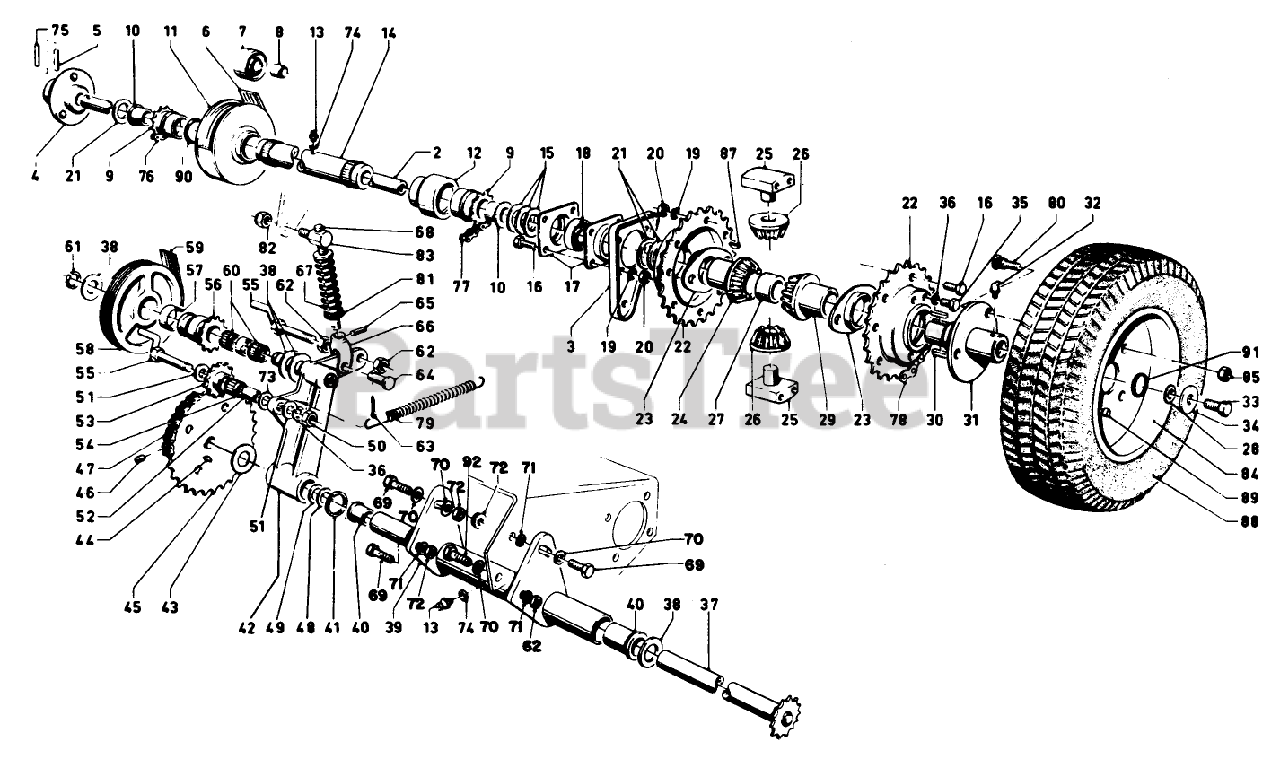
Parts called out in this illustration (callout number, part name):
4	Hub, Right Side
5	PIN-ROLL, SLOTTED
7	REEL IDLER *R
8	TOL RING
10	3/4IDX1LG FLANGE BSHG
13	FITTING-GREASE
15	WASHER-THRUST
16	SCREW-HH
19	WASHER-LOCK
20	NUT-HEX
21	THRUST WASHER
28	WASHER-LOCK, INTERNAL
30	KEY-SQUARE
32	FITTING-LUBE, 45 DEG
33	SCREW-HH
34	WASHER-FLAT
35	SCREW-HH
36	WASHER-LOCK
38	THRUST WASHER
40	Bushing
41	RING-SNAP
43	THRUST WASHER
44	KEY-WOODRUFF
45	LARGE SPROCKET ASM
46	SCREW-SET
47	TRACTION CHAIN
48	THRUST WASHER
49	THRUST WASHER
50	NUT-HEX
51	WASHER-PLAIN
52	SPINDLE
53	Sprocket, Idler (Incl. Ref. #54)
57	Ring Tolerance
58	TRACTION PULLEY
59	TRACTION BELT
60	.625 NEEDLE BEARING
62	NUT-JAM
63	PIN-COTTER
64	PIN-CLEVIS
65	PIN-ROLL, SLOTTED
66	CLEVIS
67	COMP SPRING *R
68	ROD FLANGE WA
69	SCREW-HH
70	WASHER-FLAT
71	WASHER-LOCK
73	WASHER-FLAT
74	WASHER-LOCK
75	PIN-ROLL
79	SPRING-EXTENSION
80	DRIVE STUD
81	WASHER-FLAT
82	NUT-LOCK, NI
85	LUG NUT
87	KEY-WOODRUFF
90	2-1/2X086 EX SNP RING
91	O-RING
92	SCREW-HH
